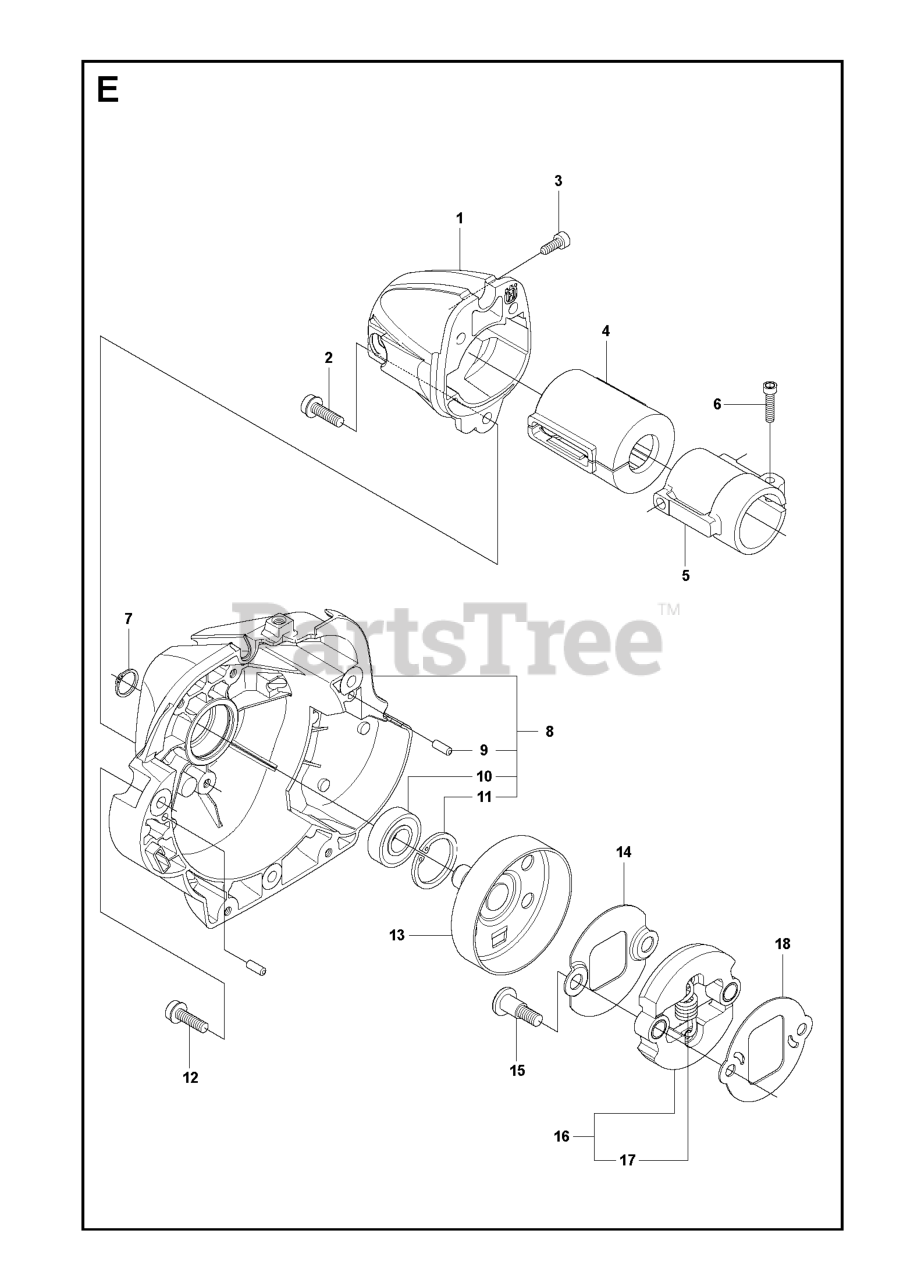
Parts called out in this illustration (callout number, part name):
2	SCREW IHSCFM
3	SCREW IHSCT
4	VIBRATION ABSORBER
5	SLEEVE, COVER
6	SCREW MC6S 5X25
7	SEEGER CLIP
8	CLUTCH COVER KPL
10	BALL BEARING
11	RETAINING RING SGH 28
12	SCREW IHSCFM
13	CLUTCH DRUM
15	SCREW CLUTCH
16	CLUTCH CPL
18	WASHER
